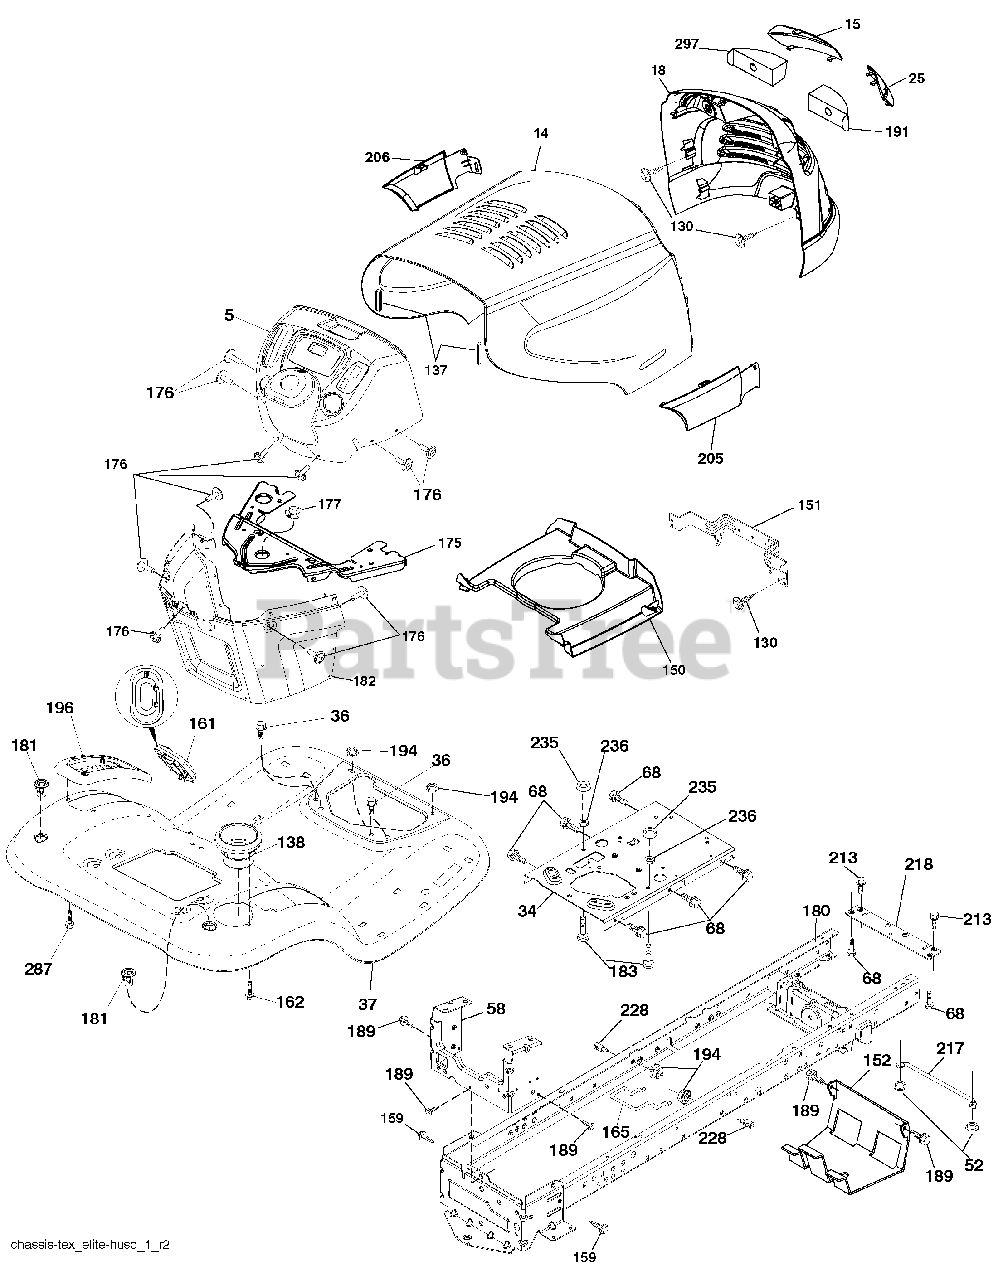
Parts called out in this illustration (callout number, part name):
14	Hood
15	Lens Grille LH
25	Lens Grille RH
34	Plate Engine
36	Screw 5/16-18 x 3/4
52	Nut Crown Lock 5/16-18
58	Drawbar Upper
68	Screw THDROL 5/16-18 x 1/2
130	Screw #10 x 0.750 BOS Thread
137	Bumper Hood
138	Cupholder
150	Duct Heat Hood
151	Bracket Pivot
152	Shield Browning/Debris
159	Screw 3/8-16 x 3/4
161	Window Fuel
162	Screw Hex Wsh Hi-Lo 1/4 x 1/2 unc
165	Support Tank Rear
175	Crossmember
176	Screw 10-24 x 5/8 Wshd Qdrx
177	Bushing Steering
180	Chassis
181	Bushing Mtg. Fender Crgo.
182	Dash Lower
183	Bolt Fin Hex 5/16-18 x 1-1/4
189	Screw 5/16-18 x 3/4
191	Insert Lens Reflective RH
194	Nut Lock Hex Flange 5/16-18
196	Console Asm. Deck Lift
213	Bolt Hex HD 5/16-18 unc x 3/4
217	Rod Pivot
218	X-Piece Hood
228	Stud Fastener
235	Spacer Fender
236	Nut Center Lock 5/16-18 unc
287	Screw Hex Washead 1/4-20 x 3/8
297	Insert Lens Reflective LH
